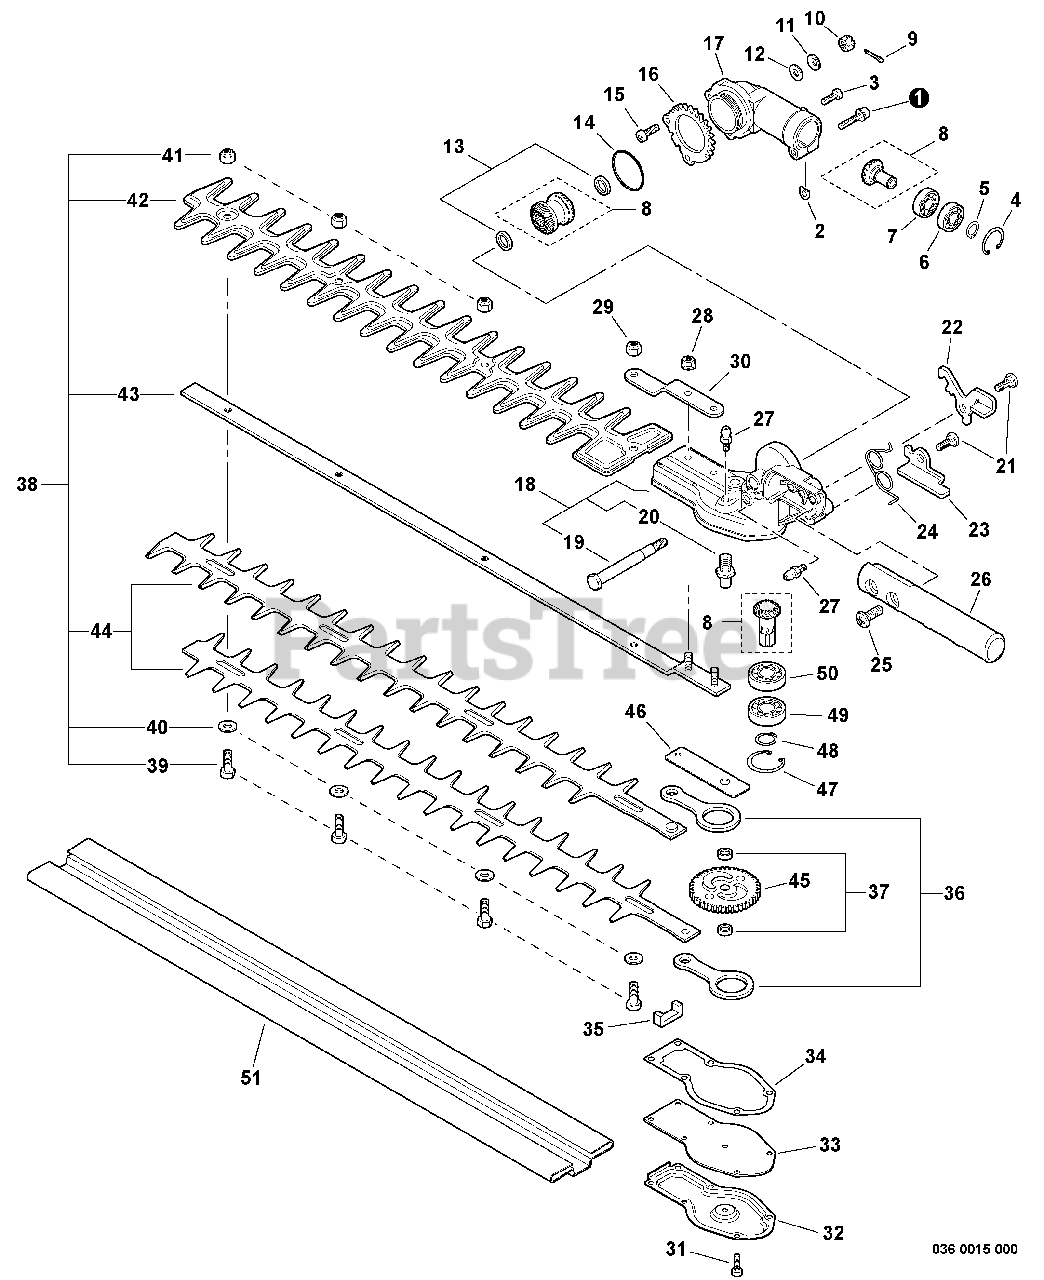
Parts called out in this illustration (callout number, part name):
1	SCREW - 5X25
3	SCREW - 5X12
4	RING, RETAINING - 24
5	RING, RETAINING - 9
6	BEARING, BALL - 609
7	BEARING, BALL - 609
8	GEAR SET
9	PIN, SPLIT - 1.6X15
10	NUT - 6
11	WASHER - CONICAL
12	WASHER - 6
13	COLLAR - 16X10X2
15	SCREW - 5X12
16	RING, LOCK
17	CASE, GEAR - UPPER
18	GEAR CASE ASSY
20	DRIVESHAFT
21	SCREW - 6
22	LEVER, LOCK
23	RELEASE, LOCK
25	SCREW - 6X20
27	FITTING, GREASE
28	NUT - 5 -- FLANGE
29	LOCKNUT - 6
30	PLATE, ANGLE
31	SCREW - 4X10
32	LID, GEAR CASE
34	GASKET, GEAR CASE
35	SEAL, FELT
36	ROD, CONNECTING
38	BLADE KIT - 22" (55cm) CHROME
39	BOLT - 6X20
40	WASHER - 6
41	LOCKNUT - 6
42	SHIELD, BLADE
43	SUPPORT, BLADE - 22" (55cm)
44	BLADE KIT - 22" (55cm) CHROME
45	GEAR, CAM
46	PLATE, GUIDE
47	RING, RETAINING - 28
48	RING, RETAINING - 12
49	BEARING, BALL - 6001ZZ
50	BEARING, BALL - 6001C3
51	COVER, BLADE
